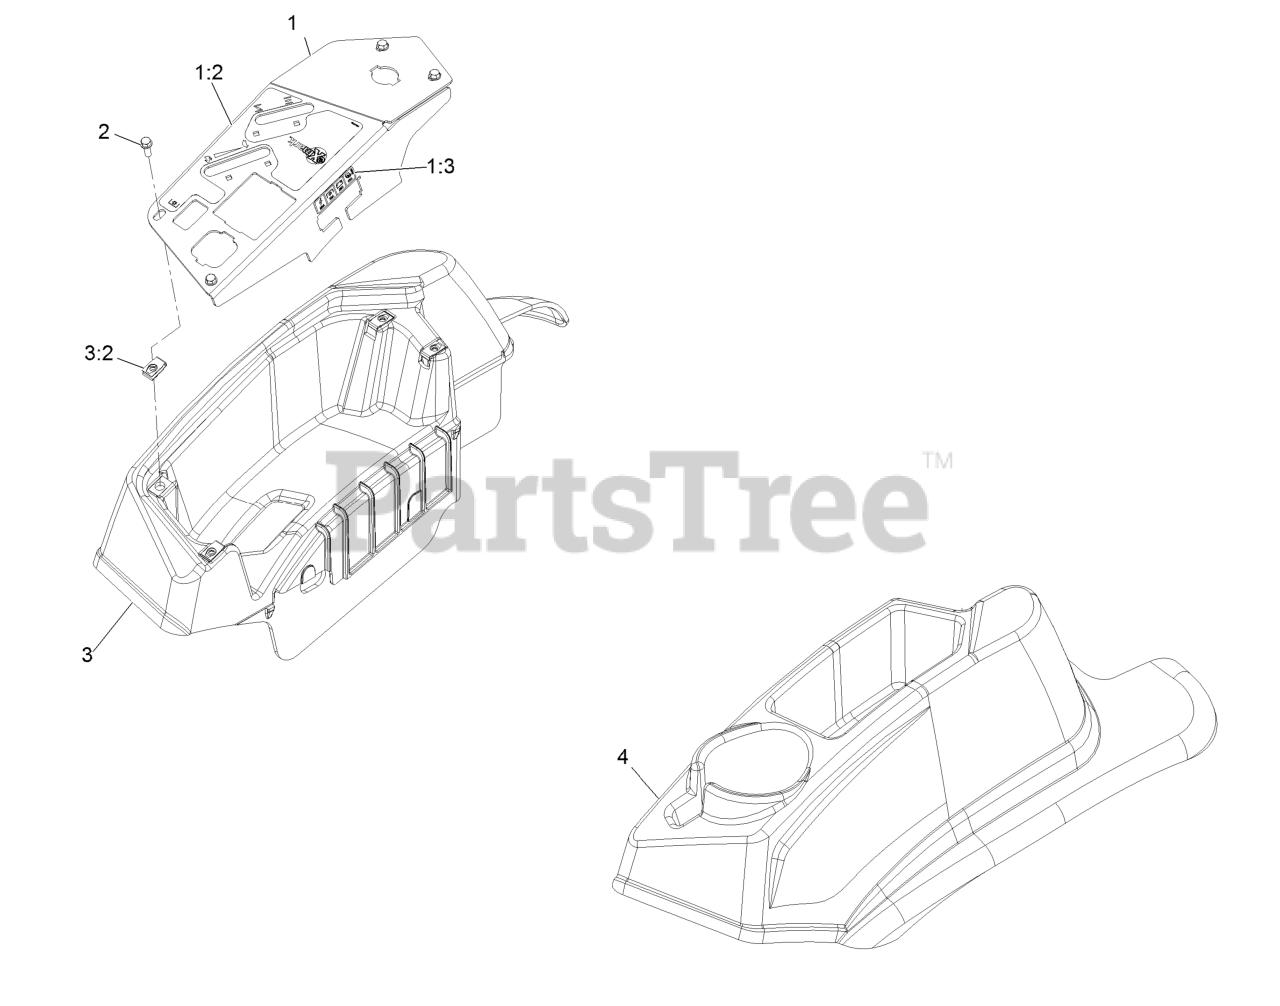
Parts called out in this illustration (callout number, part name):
1	ASM-Panel, Control W/Decal
1:2	Decal-Control Panel Non-Efi
1:3	Decal-Fuses
2	Screw-Machine 1/4-20 X 3/4
3	Console,RH As ASM
3:2	Nut-Retainer-Panel 1/4-20
4	Console, LH As
